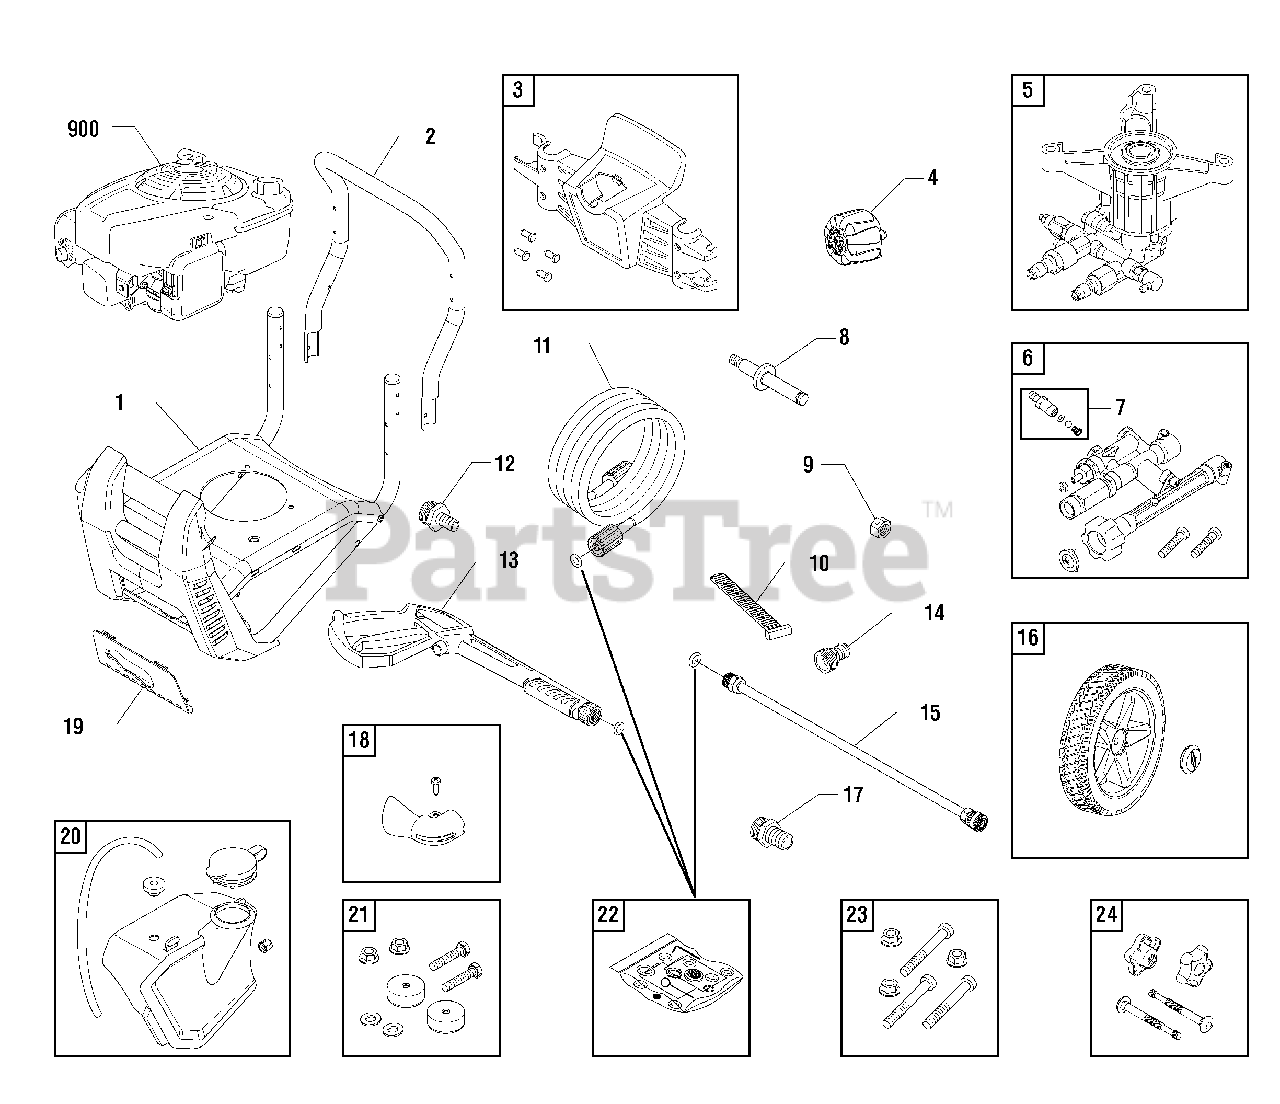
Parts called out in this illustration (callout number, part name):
5	PUMP
6	POWERFLOW
13	GUN
14	QUICK CONNECT
18	DEFLECTOR-EXHAUST
20	TANK-CHEMICAL
21	MOUNT-VIBRATION
23	KIT-HARDWARE PUMP MOUNTING
24	KIT-HARDWARE HANDLE
900	** ENGINE
